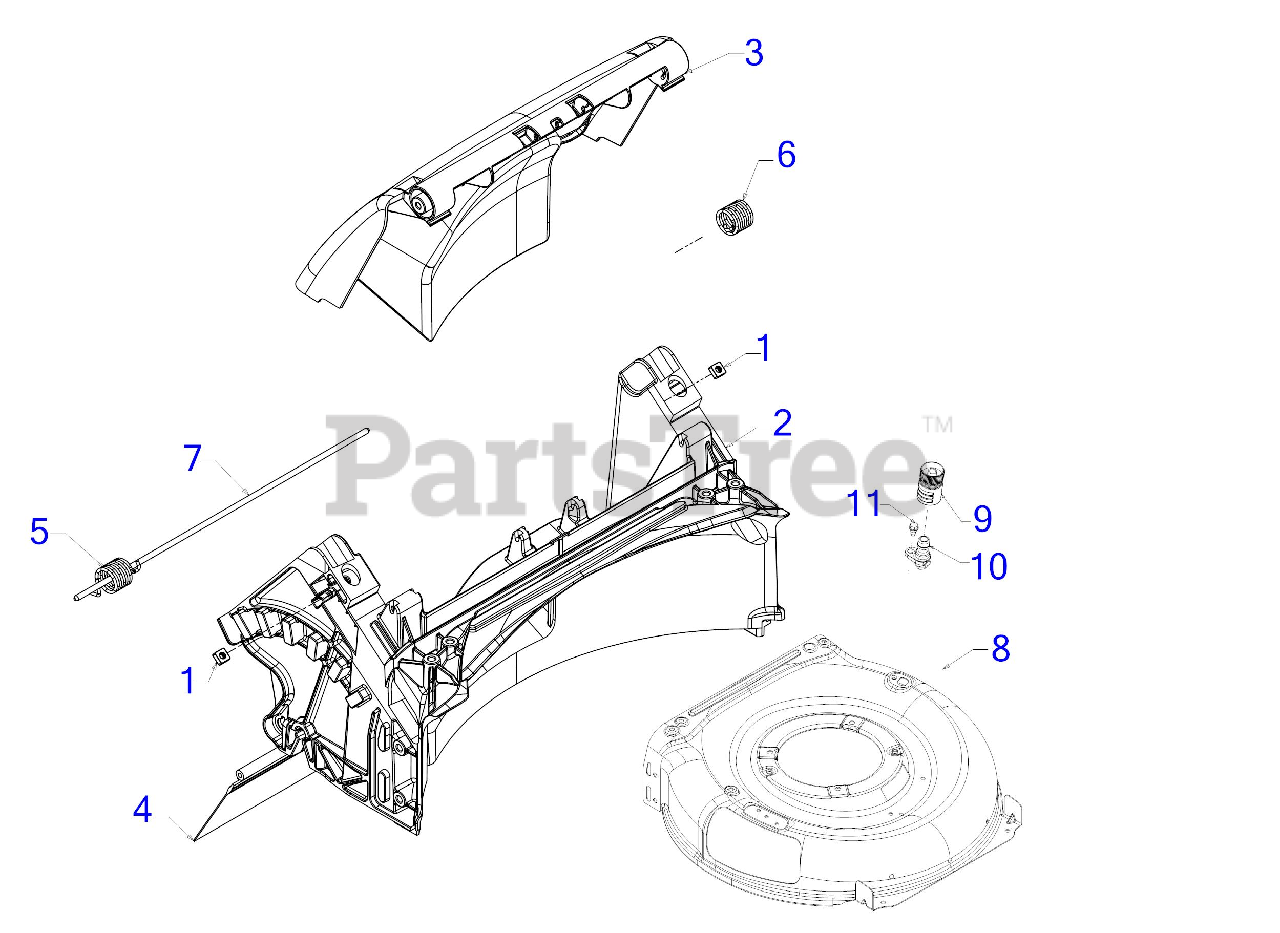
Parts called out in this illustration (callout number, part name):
1	SQUARE NUT 1/4-20
2	DOOR ASSEMBLY
3	REAR BAG DOOR ASSEMBLY
4	TRAILSHIELD
5	TORSION SPRING (RH)
6	TORSION SPRING (LH)
7	REAR DOOR PIVOT ROD
8	21" DECK (3N1)
9	WATER NOZZLE
10	DECK WASH NOZZLE
11	SHOULDER SCREW 1/4-20 x .50
